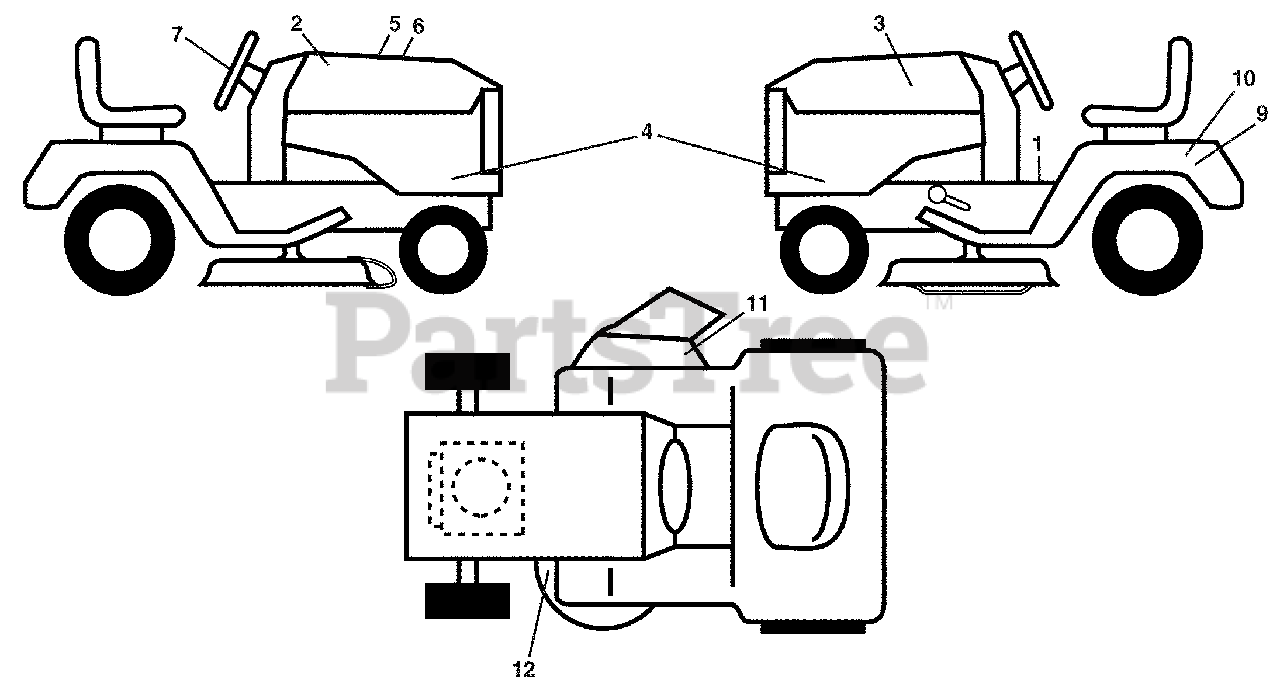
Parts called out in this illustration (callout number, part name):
1	Cap Valve Tire
2	Stem Valve
3	Rim Asm 6" Front Service
4	Tube Front
5	Tire F T 15 x 6 0 - 6
6	Fitting Grease
7	Bearing Flange
8	Cap Axle Blk 1 50 x 1 00
9	Tire R T 18 x 9.5-8 Service
10	Tube Rear
11	Rim Asm 8" rear Service
